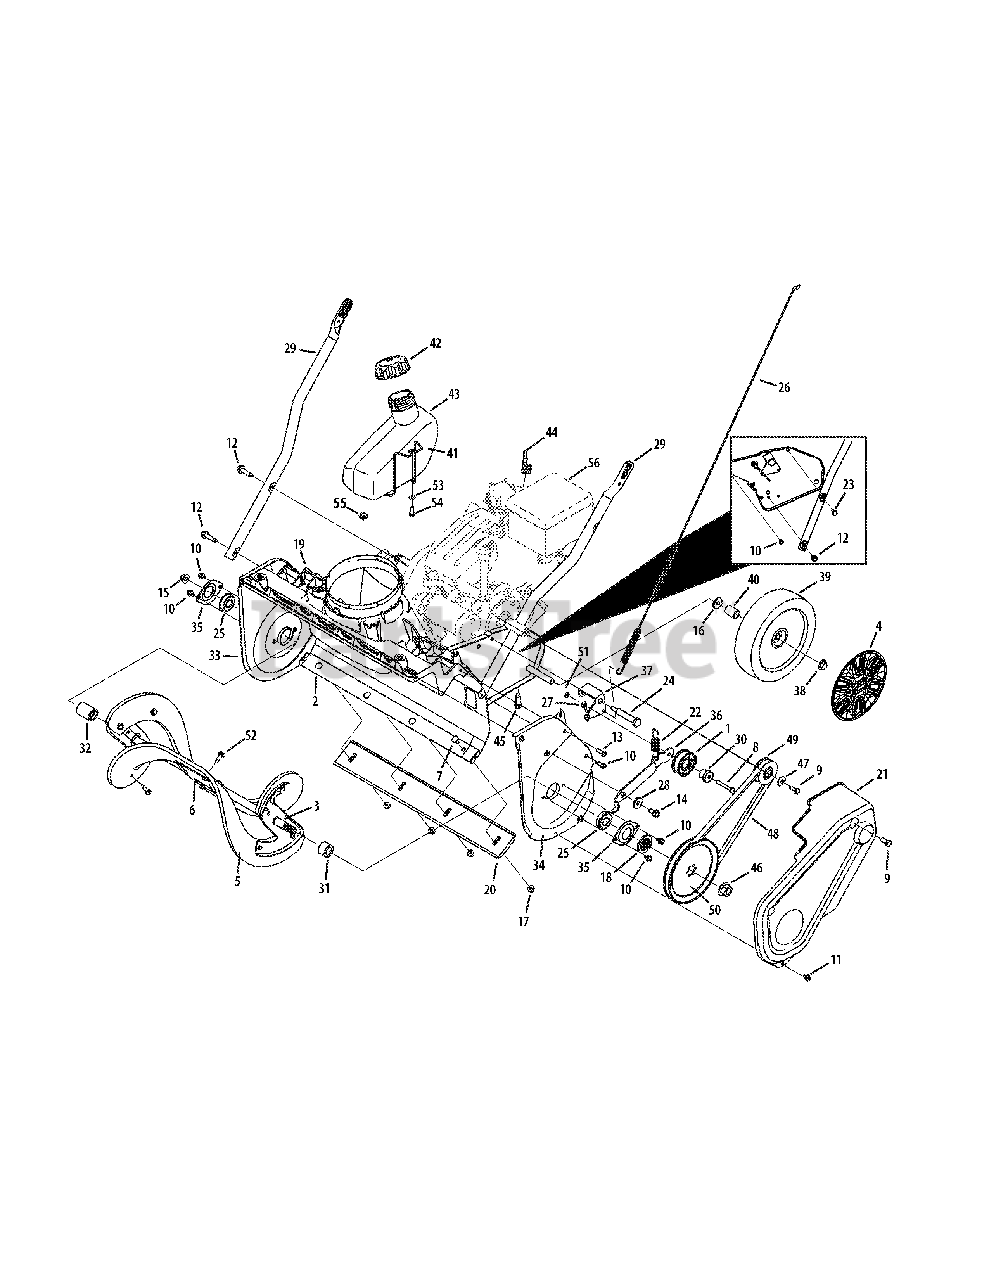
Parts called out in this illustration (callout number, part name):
1	Idler Pulley Assembly
2	Frame
3	Auger Assembly Mount
5	Auger Replacement Kit
6	Center Auger Bracket
7	Carriage Screw, 1/4-20 x .62
8	Hex Screw, 1/4-20 x 1.50
9	Hex Lock Screw, 5/16-24 x .875
10	Hex Washer Screw, 1/4-20 x .750
11	Hex Washer Screw, 1/4-20 x .500
12	Hex Washer Screw, 5/16-18 x 1.250
13	Hex Washer Screw, 1/4-15 x .750
14	Hex Washer Screw, 5/16-18 x .75
15	Flange Lock Nut, 3/8-16
16	Flat Washer, .535 x .930 x .090
17	Flange Lock Nut, 1/4-20
18	Pulley Hub
19	Chute Adapter
20	Shave Plate
22	Extension Spring, .70 x 3.035
23	Hex Screw, 5/16-24 x 1.25
24	Shoulder Bolt, 5/16-24 x .496 x 2.18
25	Ball Bearing, .500 x 40mm x 12mm
26	Clutch Cable
27	Drive Cable Wire Support
28	Shoulder Spacer
30	Shoulder Spacer, .260 x .785 x .538
31	LH Auger Spacer
32	RH Auger Spacer
33	RH Auger Plate
34	LH Auger Plate
36	Idler Bracket
37	Cable Idler Bracket
38	Push Cap, 1/2
40	Sleeve Spacer, .525 x .775 x .835
41	Gas Tank Wire Support
42	Fuel Cap
43	Fuel Tank
44	Choke Extension Lever
45	Hex Washer Screw, 3/8-16 x 1.000
46	Flange Nut, 7/16-20
47	Thrust Washer, .330 x 1.25 x .120
48	Belt, .500 x 35.06
49	Pulley Half, .625 x 2.25
50	Pulley, 1/2 x 6.00
52	Hex Washer Screw, 1/4-20 x .750
53	Washer, .265 x 1.00 x .030
54	Screw, 1/4-10 x .625
55	Hose Clamp
56	Replacement Engine
